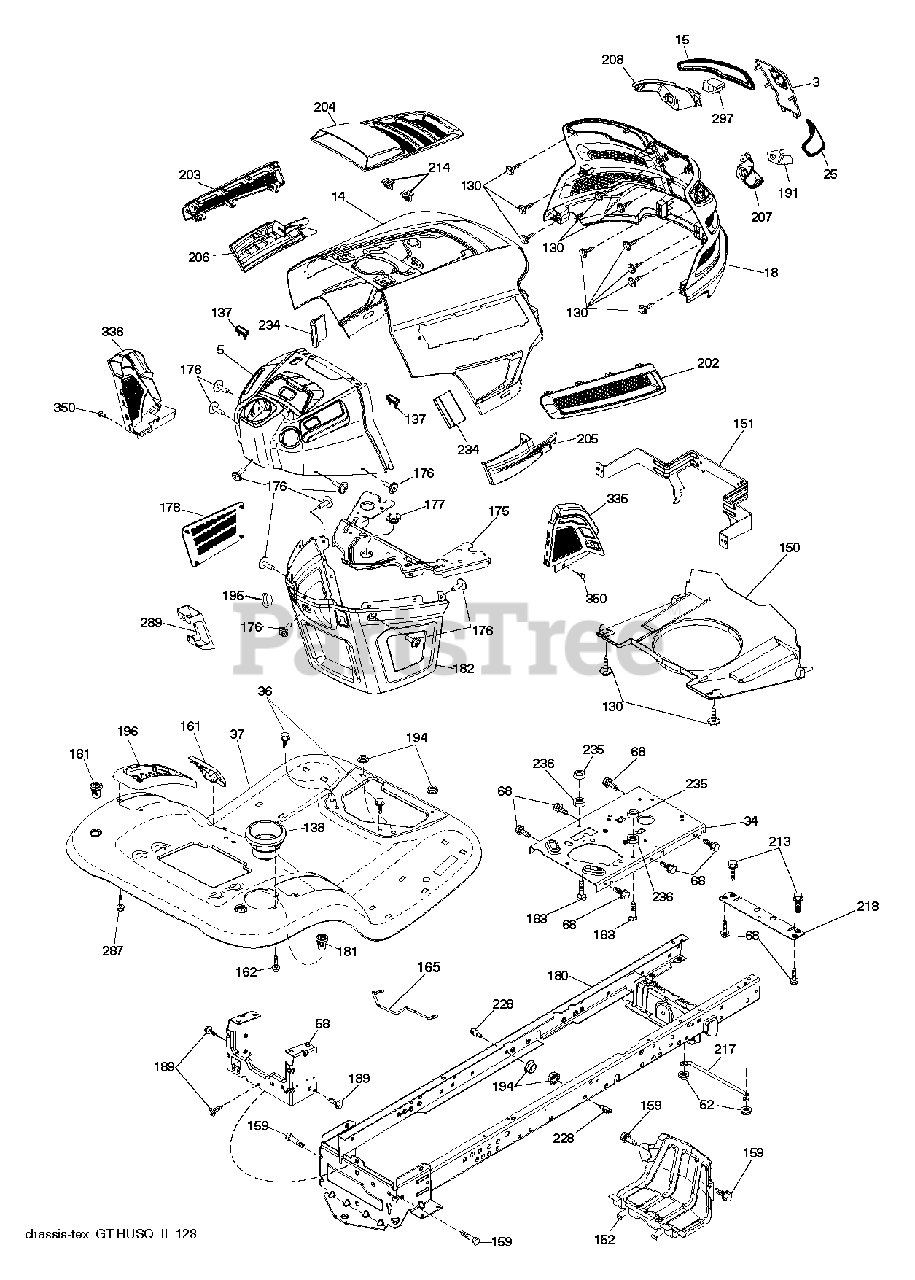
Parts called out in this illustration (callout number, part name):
3	APPLIQUE.SUBASM.GT.HUSQ.II
5	DASH.UPPER.ASSY.GT2.GREY
14	HOOD.ASM.HUSQVARNA.GT.TEX.ORAN
15	LENS.HEADLIGHT.LH.GTII.2011
18	GRILLE.SUBASM.GT.HUSQ.II
25	LENS.HEADLIGHT.RH.GTII.2011
34	PLATE.ENGINE.WELDED.CHASSIS
36	SCREW 5/16"
37	FENDER.TLT.FS.W/CPH/FW/RSF.668
52	LOCKNUT
58	DRAWBAR UPPER 2PC SMALL FENDER
68	SCREW LT
130	SCREW.#10 X 0.750.BOS
137	BUMPER DASH
138	HOLDER.CUP.LT.GREY
150	AIR DUCT.GTV2(1.66"RING HEIGHT
151	BRACKET.PIVOT.HOOD.GT.HUSQ.II
152	SHIELD.BROWNING.PNT.GT.V2
159	SCREW, 3/8-16X3/4
161	WINDOW.FUEL.LT.TEX.GREY
162	SCREW.HI-LO.CONSOLE
165	SUPPORT.TANK.REAR.W/TEX
175	PLATE.CROSSMEMBER.HUSQ
176	SCREW.#10-24X5/8.RN.QU
177	BUSHING, STEERING
178	CARGO.ASM.NET.TXGT.W/C
180	CHASS.WLDMNT.TL.12GA/2P.48/54
181	BUSHING.MNT.FEND.CRGO.TEX.49
182	DASH.LOWER.COMMON.12V.ADAPTOR
183	BOLT.5/16-18X1-1/4 FULL THD
189	SCREW
191	INSERT.REFLECTIVE.RH.HUSQ.GTII
194	NUT LOCK HEX FLANGE 5/16-18
195	PLUG.HOLE.DASH.LOWER.12V.BLK
196	DECKLFT.CONSOL FULL ASSM GREY
202	VENT.SIDE.RH.GT.HUSQ.II.
203	VENT.SIDE.LH.GT.HUSQ.II.498
204	VENT.TOP.HUSQ.GT2
205	SIDE.TRIM.RH.GT.HUSQ.II
206	SIDE.TRIM.LH.GT.HUSQ.II.GRAY
207	BEZEL LIGHT.RH.GT.II.MYLAR
208	BEZEL LIGHT.LH.GT.II.MYLAR
213	BOLT
214	CLIP.RETAINER.TINNER.
217	ROD.PIVOT.HOOD
218	X-PIECE.HOOD.STOP.NON/
228	STUD.FASTNER.W/ANTI-ROTATE
234	BUMPER.HOOD.TEX.HUSQVARNA
235	SPACER FENDER
236	NUT.CENTERLOCK.5/16-
287	SCREW 1/4X20
289	PLUG.N/CRUISE.COMMON.YT/GT.BLK
297	INSERT.REFLECTIVE.LH.HUSQ.GTII
335	COVER.LOWER.DASH.RH.BLACK
336	COVER-LH.LOWER.DASH.GT2.BLACK
350	CLIP.X-MAS.TREE
